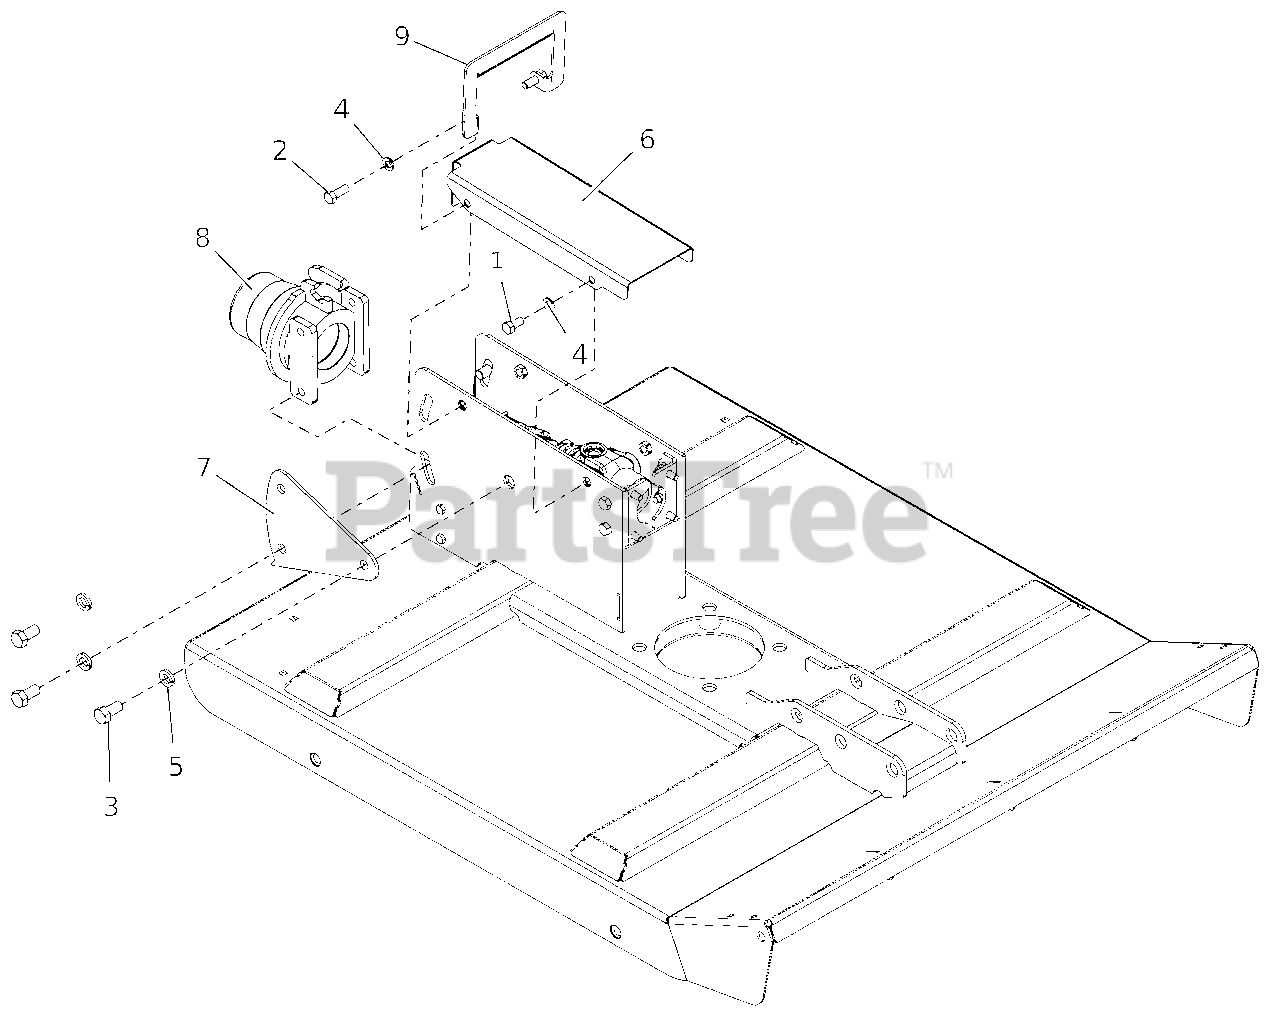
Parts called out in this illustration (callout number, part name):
1	BLT,HEX .38-16X.75 G5 ZCC
2	BLT,HEX .38-16X1.00 G5 ZCC
3	BLT, HEX .50-13X1.00 G5 ZCC
4	WSHR,LK-REG .375X.094 ZCC
5	WSHR,LK-HVY .500X.151 ZCC
6	COVER, TOP
7	PLATE, PIVOT
8	WLDMT, INPUT DRIVE
9	HANDLE, LIFT
